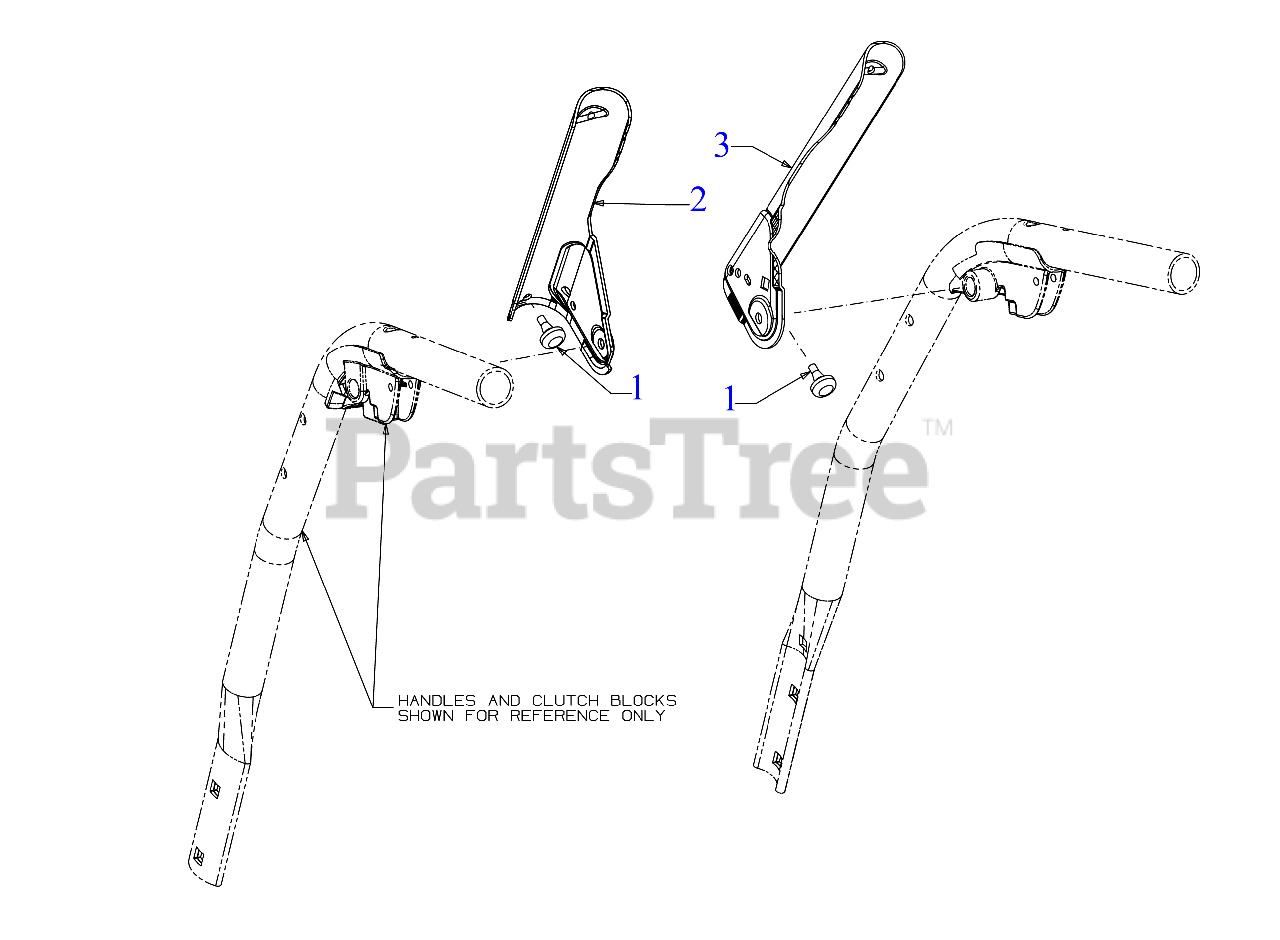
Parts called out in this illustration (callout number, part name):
1	RUBBER BUMPER
2	ENGAGEMENT HANDLE (LH) (POWDER BLACK)
3	ENGAGEMENT HANDLE (RH) (POWDER BLACK)
